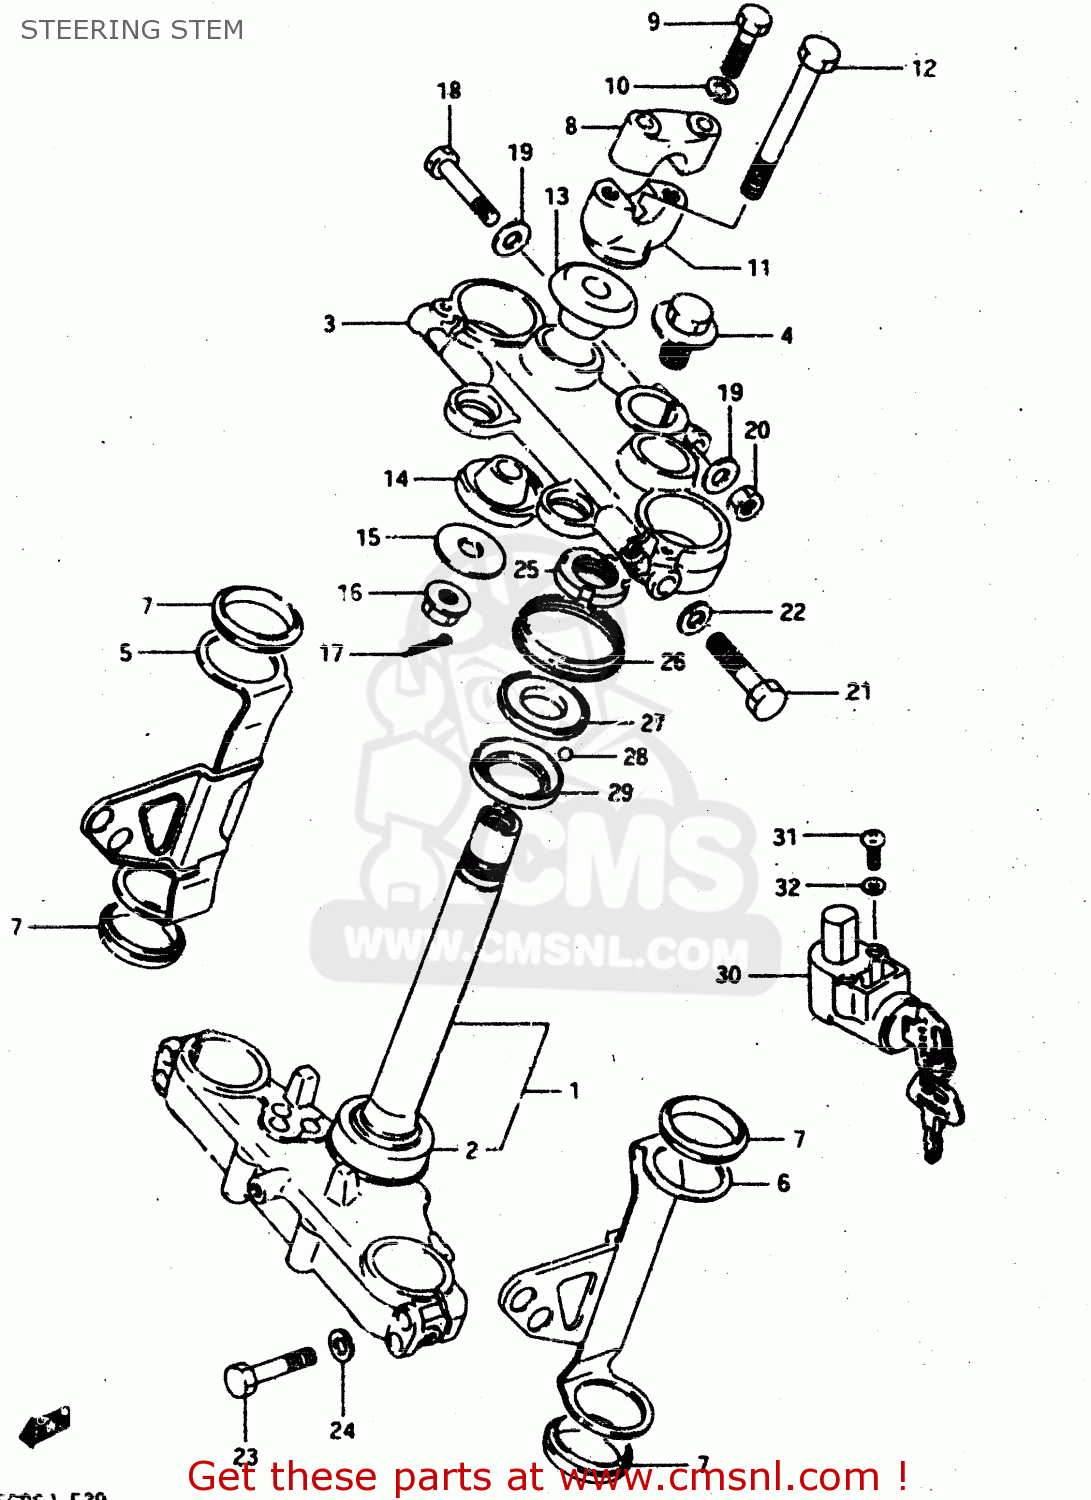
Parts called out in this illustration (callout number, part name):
1	STEM,STEERING
2	BEARING
3	HEAD,STEERING STEM
4	BOLT,STEERING STEM
5	COVER,FORK,RIGHT
6	BRACKET,HEADLAMP,LEFT
7	CUSHION,HEAD LAMP BRACKET
8	HOLDER,HANDLEBAR
9	BOLT
10	LOCK WASHER
11	HOLDER,HANDLE LWR
12	BOLT,HANDLE HOLDER
13	DAMPER,UPR
14	DAMPER,LWR
15	WASHER,HANDLEBAR HOLDER
16	NUT
17	COTTER PIN
18	BOLT
19	WASHER
20	NUT ,8MM
21	BOLT
22	LOCK WASHER
23	BOLT
24	LOCK WASHER
25	NUT,STEERING STEM
26	SEAL,STEERING UPR DUST
27	RACE,STEERING,OUTER,UPPER
28	BALL
29	RACE,STEERING INNER (SUJ)
30	LOCK ASSY,STEERING
31	SCREW
32	LOCK WASHER
